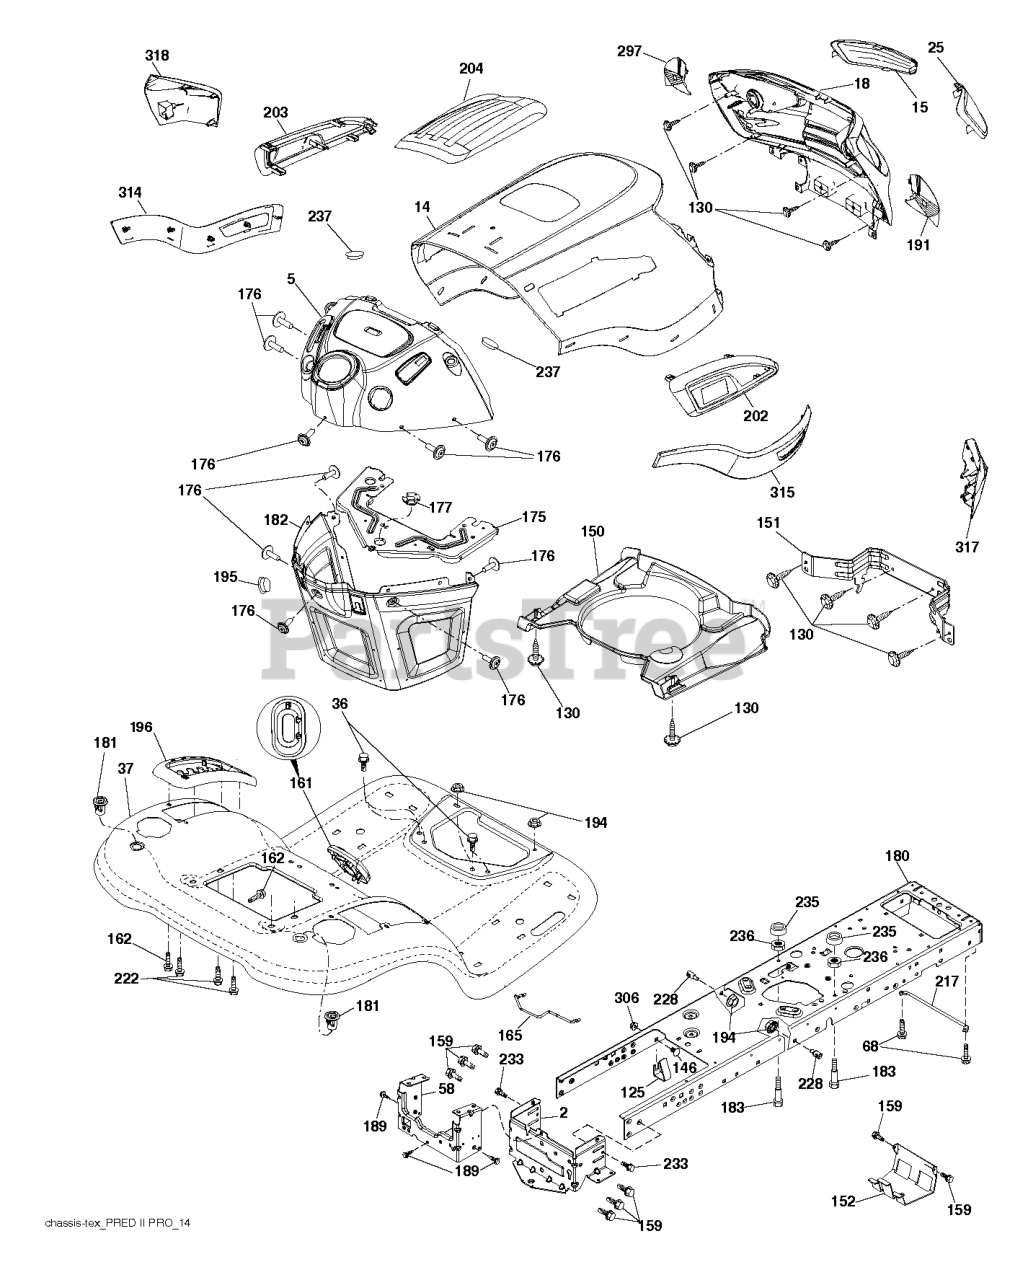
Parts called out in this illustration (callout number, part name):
2	DRAWBAR.LOWER.2PC,20"TIRES
5	DASHBOARD DASH.YT.PRED.REC.GA.
14	HOOD HOOD.GRILL.PREDII.YT/GT.Y
15	LENS.LH.PRED II.YT.CLR.SVC
18	GRILLE.PRED2.GT.PRO.REDMAX
25	LENS.RH.PRED II.YT.CLR.SVC
36	SCREW 5/16"
37	FENDER FENDER PNT CONVERSION 4
58	DRAWBAR.UPPER.2PC,LRG.FENDER
68	SCR 5/16-18 X 1/2 SELFTAP ZN
125	CLIP.FUEL.LINE
130	SCREW.#10 X 0.750.BOS
146	BOLT.RDHD.SHT.SQNK.3/8-16X5/8
150	PREDATOR.YT.GT.HOOD.AIR DUCT
151	BRACKET.PIVOT.PREDATOR
152	SHIELD.BROWNING/DEBRIS
159	SCREW, 3/8-16X3/4
161	CONSOLE.FUEL.WINDOW.STGT.BLACK
162	SCREW.HI-LO.CONSOLE
165	SUPPORT.TANK.REAR.B/TE
175	PLATE.CROSSMEMBER.HUSQ
176	SCREW.#10-24X5/8.RN.QU
177	BUSHING STEERING
180	CHASSIS.TEX.BOLTED
181	BUSHING.MNT.FEND.CRGO.
182	DASH.LOWER.COMMON.12V.ADAPTOR
183	BOLT.5/16-18X1-1/4 FULL THD
189	SCREW
191	INSERT INSERT.REFLECTIVE.RH
194	NUT LOCK HEX FLANGE 5/16-18
195	PLUG.HOLE.DASH.LOWER.12V.BLK
196	CONSOLE ASM DECK LIFT BLACK
202	VENT SIDE. HOOD. PREDATOR II.
203	VENT SIDE. HOOD. PREDATOR II.
204	VENT ASM.TOP.PRED GT PRO.428
217	ROD.PIVOT.HOOD
222	SCREW.1/4-20X5/8
228	STUD.FASTNER.W/ANTI-ROTATE
233	BOLT.SHOULDER
235	SPACER FENDER
236	NUT.CENTERLOCK.5/16-
237	PLUG.MOUNT.CARGO.BLK
297	INSERT INSERT.REFLECTIVE.LH
306	NUT LOCK FLG 3/8-16 UNC
314	TRIM SUBASM. PREDATOR II. YT/G
315	TRIM SUBASM. PREDATOR II. YT/G
317	BUMPER CORNER. PREDATOR II. GT
318	BUMPER CORNER. PREDATOR II. GT
